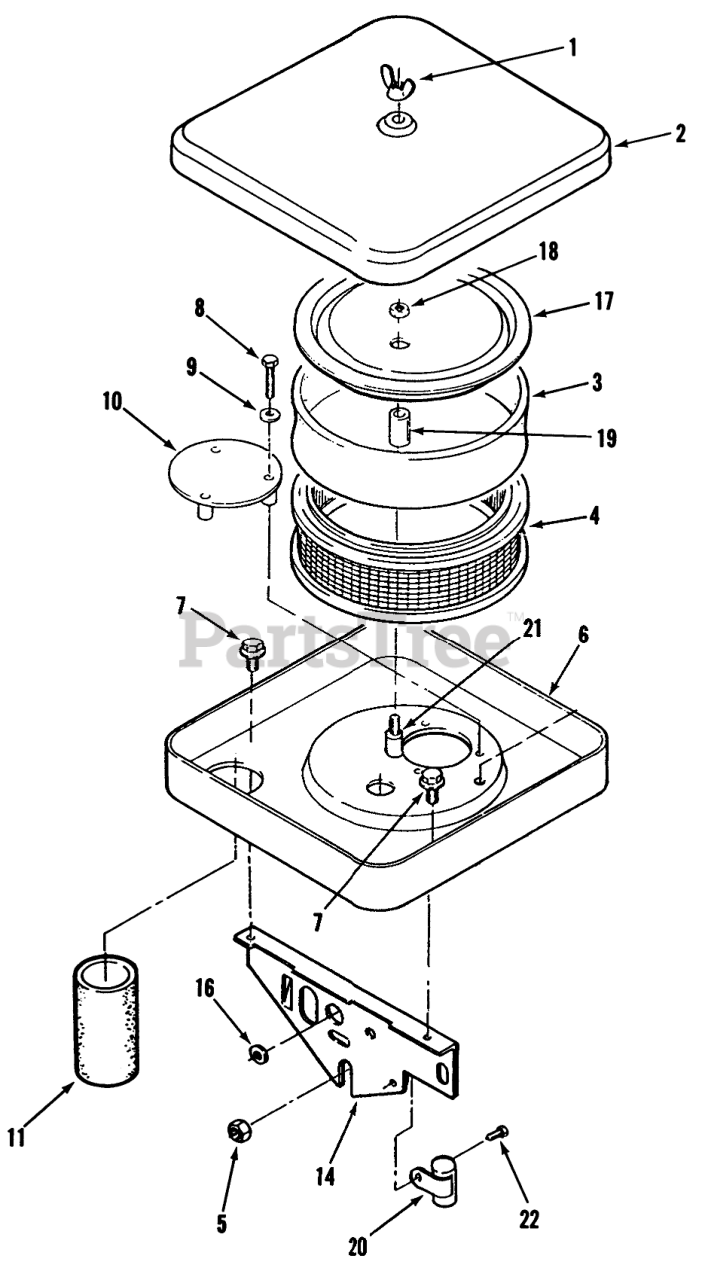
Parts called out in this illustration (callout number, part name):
1	Nut-Wing
2	CHROME-AIR CLEANER
3	AIR CLEANER ELEMENT
4	Air Cleaner Element
5	Nut
6	AIR CLEANER HOUSING
7	Screw 1/4-20 x 3/8
8	Screw Hex Hd. #10-32 x 1-1/2
9	Flat Washer #10
10	AIR DEFLECTOR PLATE
11	AIR INTAKE TUBE
14	AIR CLEANER SUPPORT
16	Grommet
17	Element Cover
18	Hex Nut 1/4-20
19	Spacer
20	Condenser
22	SCREW #10-32 X 5/8
